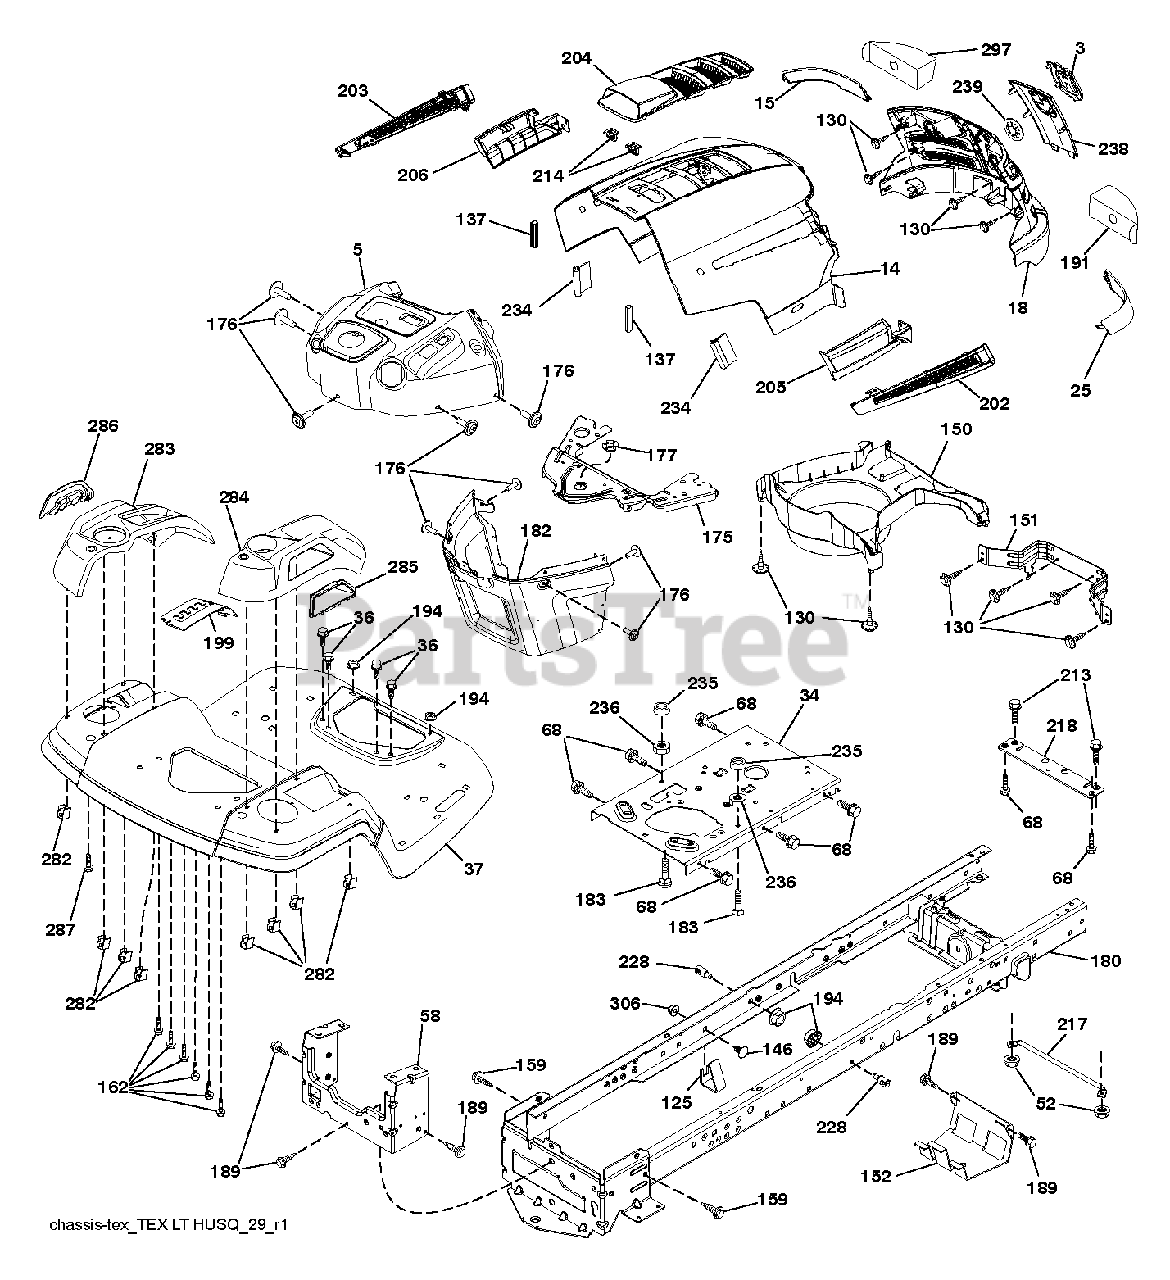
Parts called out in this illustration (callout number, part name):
3	RP LOGO
5	SUBASM.DASH.UPPER.W/BUMPER
14	HOOD.HUSQVARNA.LT.ORANGE
15	LENS RH
18	GRILLE.SVC.HUSQVARNA.GREY
25	LENS LH
34	PLATE.ENGINE.WELDED.CHASSIS
36	SCREW 5/16"
37	FENDER.TLT.FS.W/CUPHLD.ORANGE
52	LOCKNUT
58	DRAWBAR UPPER 2PC SMALL FENDER
68	SCREW LT
125	CLIP.FUEL.LINE
130	SCREW.#10 X 0.750.BOS
137	BUMPER DASH
146	BOLT.RDHD.SHT.SQNK.3/8-16X5/8
151	BRACKET PIVOT
152	SHIELD.BROWNING.W/TEX
159	SCREW, 3/8-16X3/4
162	SCREW.HI-LO.CONSOLE
175	CROSSMEMBER
176	SCREW.#10-24X5/8.RN.QU
177	BUSHING STEERING
180	CHASSIS.WLDMNT.14GA.2PC.18".TI
182	DASH.LOWER.PREDATOR LT
183	BOLT.5/16-18X1-1/4 FULL THD
189	SCREW
191	INSERT.REFLECTIVE.RH.
194	NUT LOCK HEX FLANGE 5/16-18
199	PLATE.DECK.LIFT.HUSQ.LT
202	VENT SIDE HOOD LH
203	VENT.SIDE.HUSQVARNA.LT.LFT
204	SUBASM.TOP.VENT.HUSQ.LT
205	SKIRT.SIDE.HUSQVARNA.LT.RT
206	SKIRT.SIDE.HUSQVARNA.LT.LEFT
213	BOLT
214	CLIP.RETAINER.TINNER.
217	ROD.PIVOT.HOOD
218	X-PIECE.HOOD.STOP.NON/
228	STUD.FASTNER.W/ANTI-ROTATE
234	BUMPER.HOOD.TEX.HUSQVARNA
235	SPACER FENDER
236	NUT.CENTERLOCK.5/16-
238	TRIM.HUSQ LT.668
282	CLIP.RETAINER.CONSOLE.LT.HUSQ
283	CONSOLE.ASM.LFT.RSF.HUSQ.LT
284	CONCOLE.CNTRL.PDL.HUSQ.LT.498
285	CONSOLE INSERT RH
286	CONSOLE.INSRT.LH.HUSQ.LT.BLACK
287	SCREW 1/4X20
297	INSERT REFLECTIVE
306	NUT LOCK FLG 3/8-16 UNC
